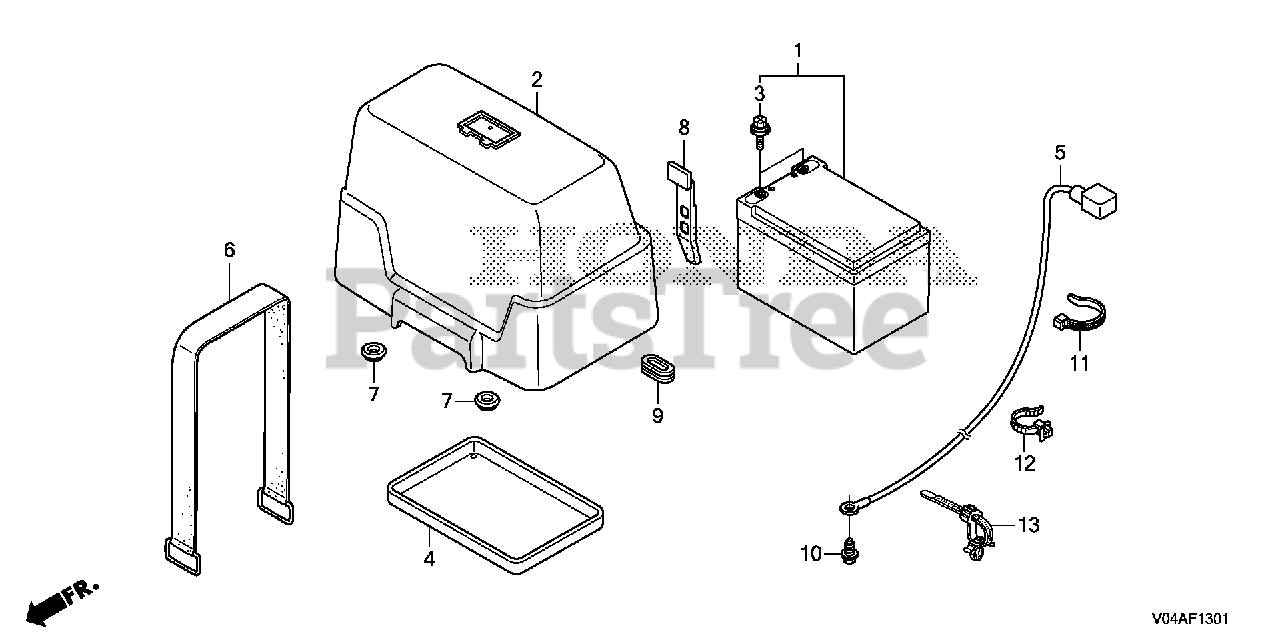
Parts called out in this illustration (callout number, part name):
1	BATTERY (HR12-12) (MSDS)
2	COVER, BATTERY *NH1* (BLACK)
3	BOLT-WASHER (5X10)
4	RUBBER, BATTERY
5	CABLE ASSY., GROUND
6	BAND, BATTERY
7	GROMMET, COVER
8	BELT, ENGINE COVER
9	GROMMET A, SIDE COVER
10	BOLT, FLANGE (6X12) (CT200)
11	BAND, WIRE (165MM) (BLACK)
12	CLIP, HARNESS BAND (145MM) (BLACK)
13	BAND, WIRE HARNESS
